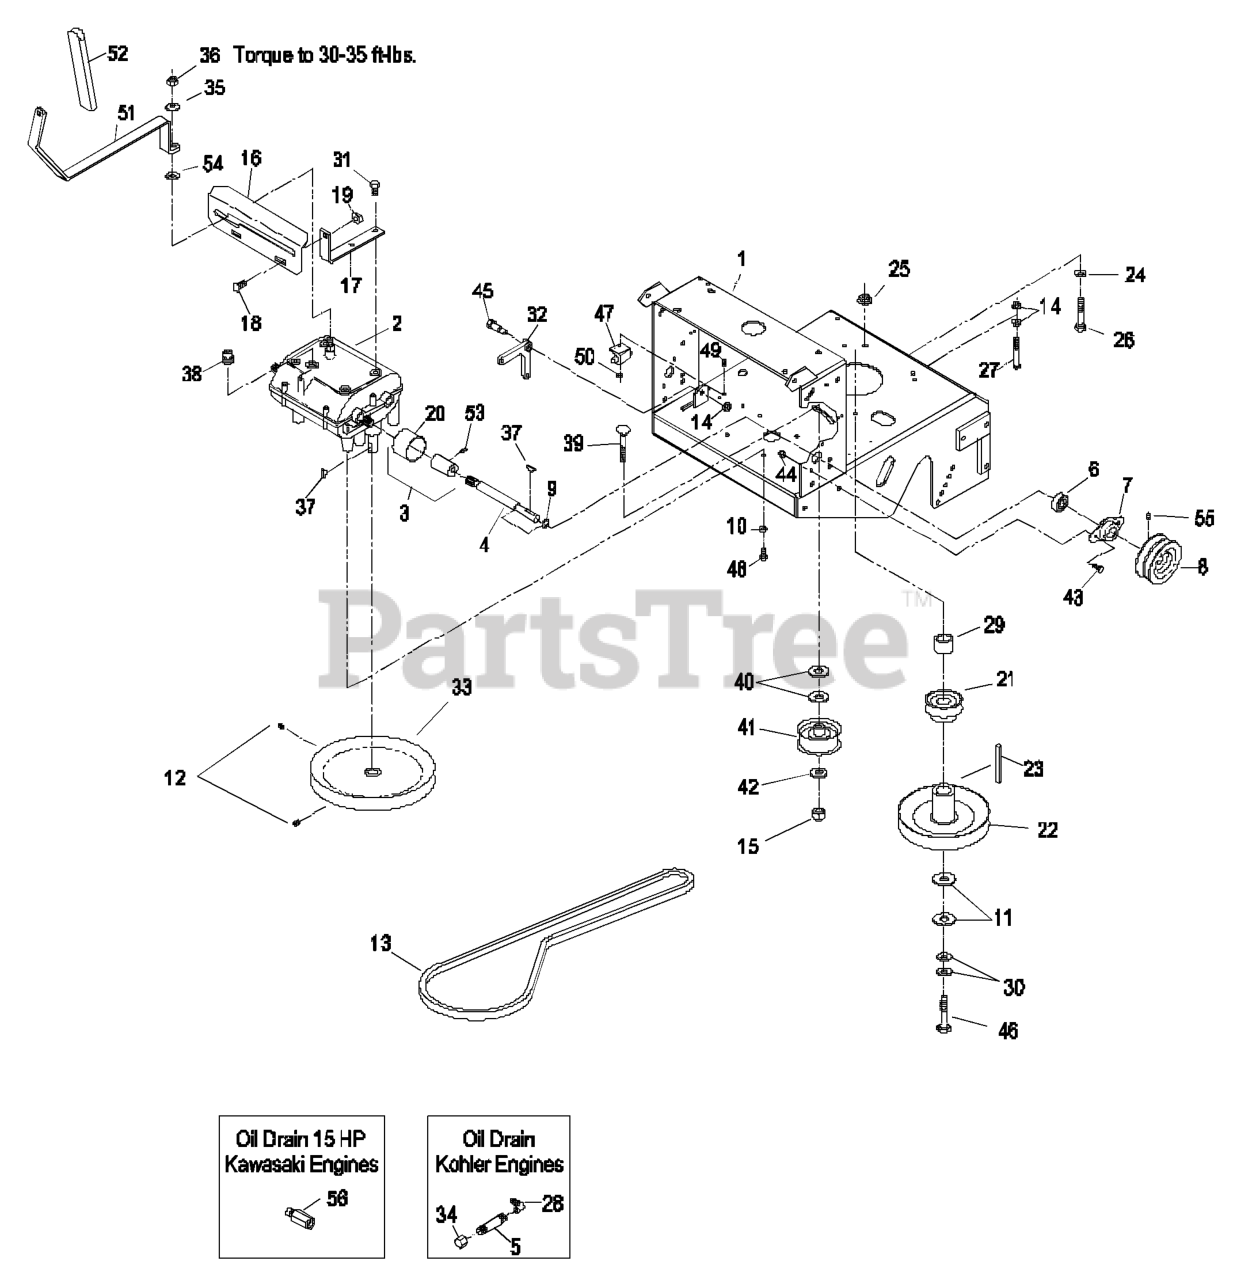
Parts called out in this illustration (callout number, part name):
1	Rear Deck
3	ASM,COUPLER/ZERK
4	SHAFT-TRANSMISSION
6	BEARING-SHAFT
7	FLANGE-OUTPUT
9	RING-RETAINING
10	WASHER-LOCK
12	SCREW-HSH
13	BELT,TRANS DRIVE
14	NUT-HHF, WHIZ
15	NUT-LOCK, NI
17	BRACKET-PLATE, SHIFT
18	BOLT-CARR
20	GUARD-COUPLER
21	SHEAVE-TRANSMISSION
23	KEY-SQUARE
24	WASHER-SPRING
26	SCREW-HH
27	SCREW-HH
28	FITTING-ELBOW-90
29	SPACER-CLUTCH
30	WASHER-SPRING
31	SCREW-HWH, THREAD CUT
32	BELLCRANK
33	SHEAVE-TRANSMISSION
34	CAP-HEX
35	WASHER-BELLEVILLE
36	NUT-LOCK
37	KEY-WOODRUFF
38	SWITCH-START, NEUTRAL
39	SCREW-HH
40	WASHER-FLAT
42	WASHER-FLAT
43	SCREW-HH
44	NUT-LOCK, NI
45	BOLT-SHOULDER
46	SCREW-HH
47	SWITCH-OPEN, NORMALLY
48	SCREW-HH
49	SCREW-PPH
50	NUT-LOCK, NI
51	ASM,SHIFT LEVER
52	GRIP,FOAM
53	FITTING-GREASE
55	SCREW-SET
56	ADAPTER
